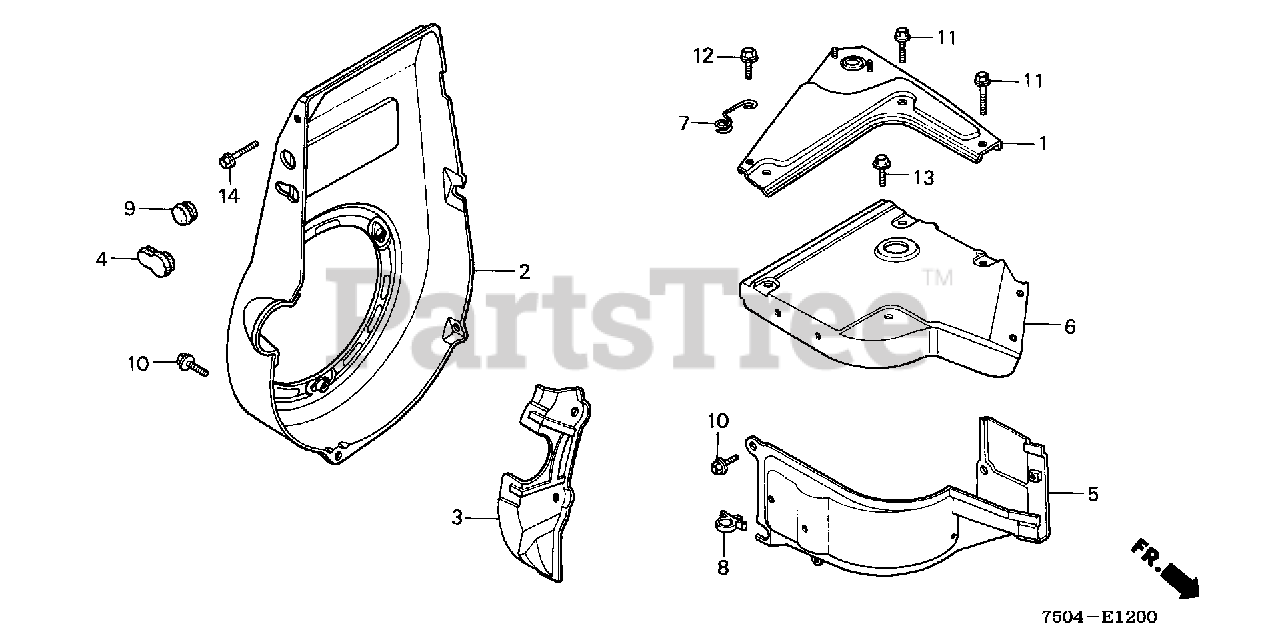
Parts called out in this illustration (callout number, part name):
1	STAY, AIR CLEANER (NOT AVAILABLE)
2	COVER, FAN *R8* (BRIGHT RED)
3	PLATE, SIDE
4	GROMMET, FAN COVER
6	COVER, TOP
7	CLAMP, IGNITION TUBE
8	CLIP, IGNITION WIRE (8MM)
9	GROMMET, DRAIN HOLE
10	BOLT, FLANGE (6X12) (CT200)
11	BOLT, FLANGE (6X28)
12	BOLT, FLANGE (6X12)
13	BOLT, FLANGE (8X20)
14	BOLT, FLANGE (6X16)
